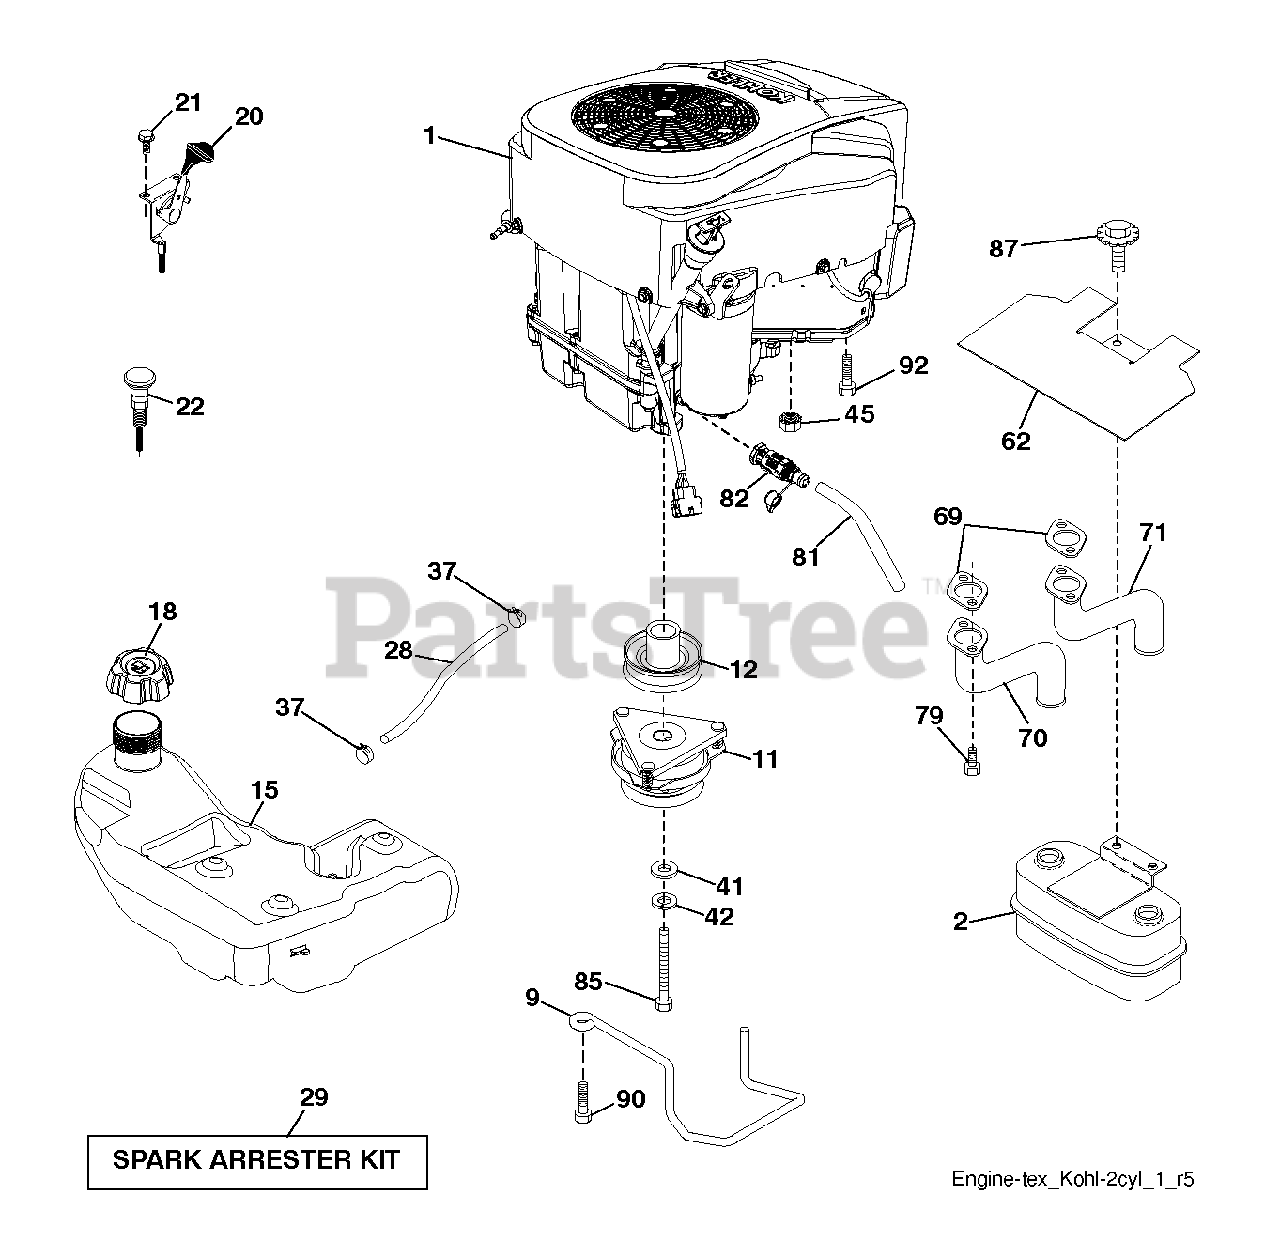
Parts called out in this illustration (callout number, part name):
2	MUFFLER.ASM.TWN.EXTNDED.DFLCTR
9	KEEPER.BELT.ENGINE.4.2
11	CLUTCH.ELECTRIC.LT.48"*
12	PULLEY.ENGINE.TUFFTORQ
15	TANK.ASSY.3.GAL.EPA
18	CAP.ASM.FL.RITCH.3"E10.SYM.498
20	THROTTLE CONTROL
21	SCREW.#10 X 0.750.BOS
22	CONTROL.CHOKE.ERGO.PUSH-IN.BLA
28	LINE.FUEL.64"REAR.EMIS
29	KIT.SPARK ARRESTOR 794945 B&S
37	HOSE CLAMP
42	LOCKWASHER
45	NUT
62	SHIELD.HEAT.MUFFLER
69	GASKET.EXHAUST.KOHL.CV18-CV26
70	RP.PIPE-EXHAUST LH
71	RP.PIPE-EXHAUST RH
79	SCREW.SOCKET HD.5/16-1
81	TUBE, DRAIN OIL ASM.
82	VALUE.OIL.DRAIN
85	BOLT HEX 7/16-20X4-1/4"
87	Bolt, 5/16-18 X 1-3/4
90	SCREW 3/8-16X1
92	SCREW 3/8-16X1
